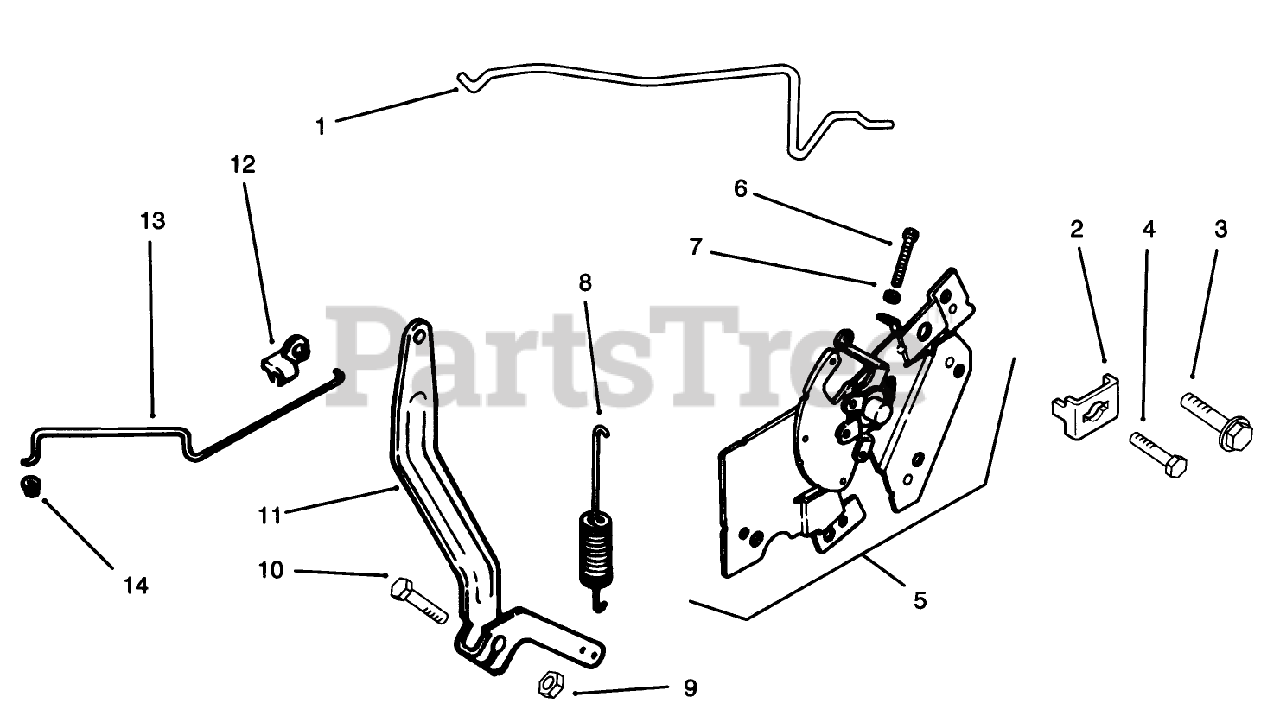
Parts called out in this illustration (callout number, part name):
1	Linkage-Choke (Only On: 72042,72043,72062,72063)
4	Screw M5x0.8x16 (Only On: 72042, 72063, 72062, 72043)
5	Control-ASM INC 6-7 (Only On: 72042, 72063, 72062, 72043)
6	Screw-HHF M4x0.7x28 (Only On: 72042, 72063, 72062, 72043)
7	Nut
8	Spring-Governor (Only On: 72042, 72063, 72062, 72043)
11	Lever-Governor (Only On: 72042, 72063, 72062, 72043)
12	Bushing-Linkage
13	Linkage-Throttle (Only On: 72042, 72063, 72062, 72043)
14	Bushing
